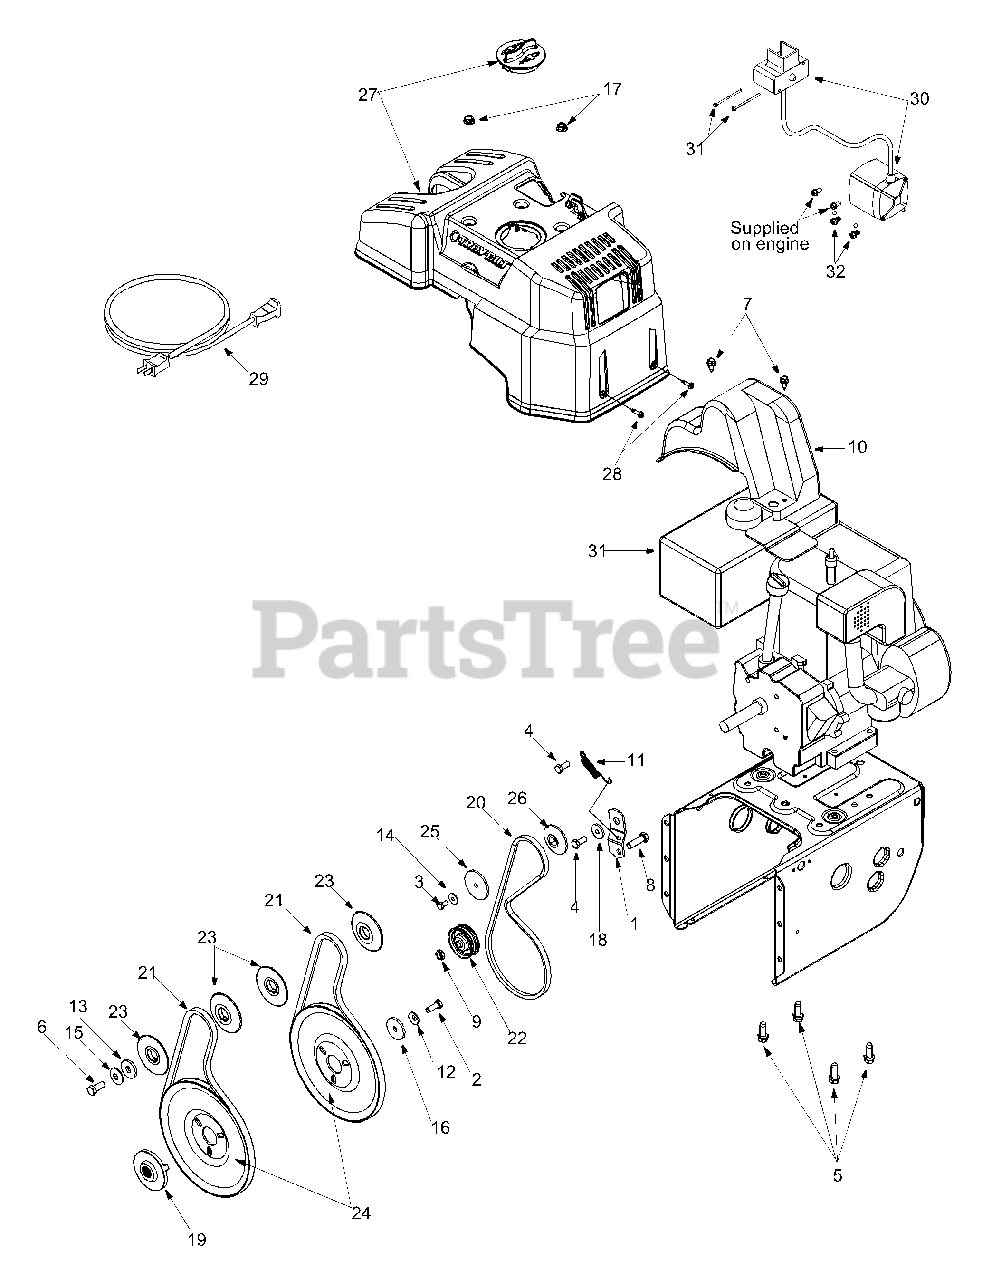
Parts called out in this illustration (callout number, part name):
3	Hex Screw 1/4-28 x.50"
4	Hex Screw 5/16-24 x.750"
5	TT Screw 3/8-16 x 1.0"
6	Hex Screw 3/8-24 x.875"
7	TT Screw 1/4-20 x.625"
8	Hex Screw 3/8-16 x 1.25"
10	Belt Cover
11	Extension Spring
12	Bell Washer
13	Flat Washer.406 x 1.25
14	Bell Washer.265 x.75 x.062
15	Bell Washer.390 x 1.13 x.062
16	Flat Washer.34 x 1.5 x.150
17	Flange Lock Nut 5/16-18
18	Shoulder Spacer
19	Pulley
20	V-Belt
21	Belt
22	Flat Idler Pulley
23	Pulley Half
24	Auger Pulley
25	Pulley Half
26	Pulley Half
27	Shroud
28	Hex Screw #10-16 x.75"
29	Extension Cord
30	Electric Starter
31	Hex Screw #6-32 x 2.5
32	Hex Screw 1/4-20 x.500
